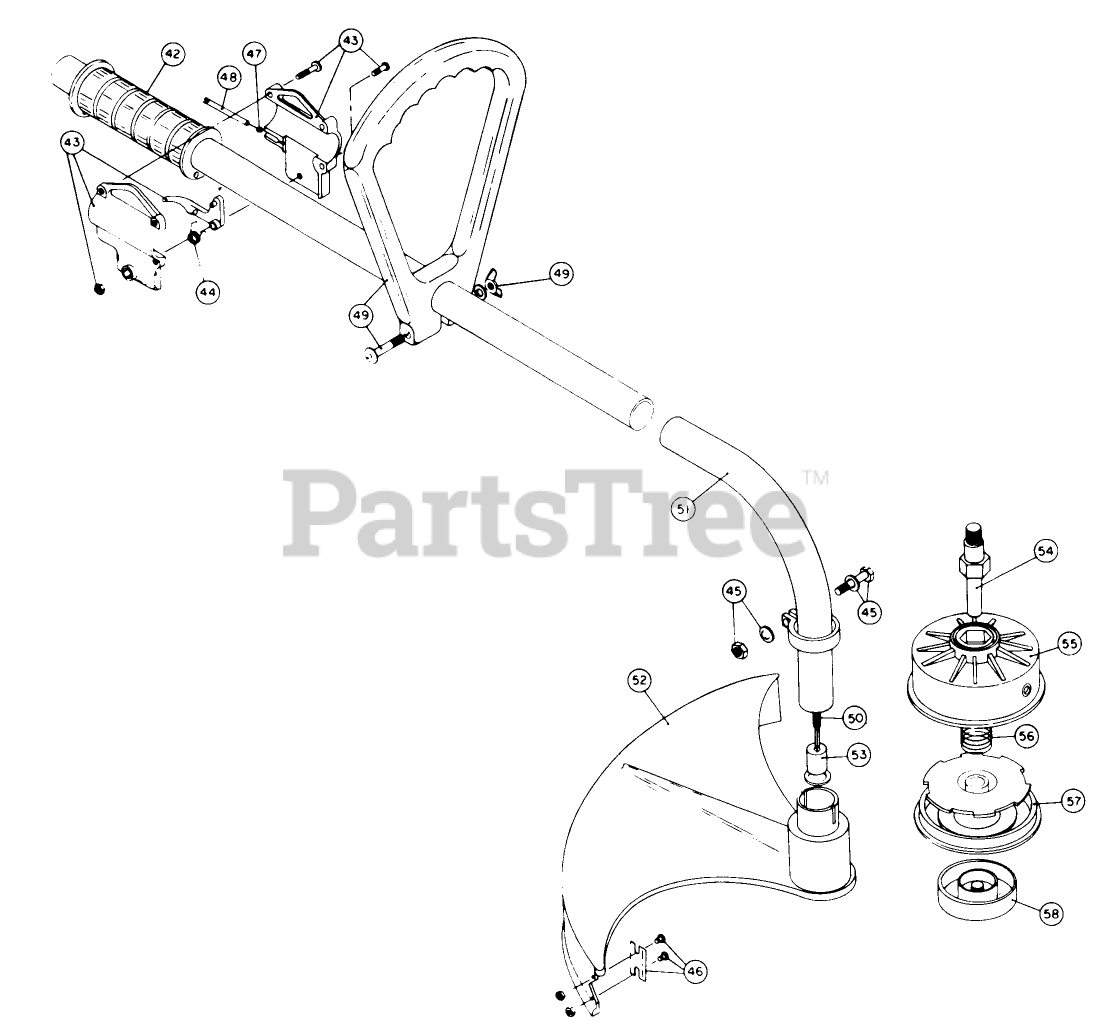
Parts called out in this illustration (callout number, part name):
44	THROTTLE TRIGGER SPRING
46	BLADE ASM
47	THROTTLE CABLE WIRE
48	THROTTLE CABLE HSG
57	REEL - INNER
